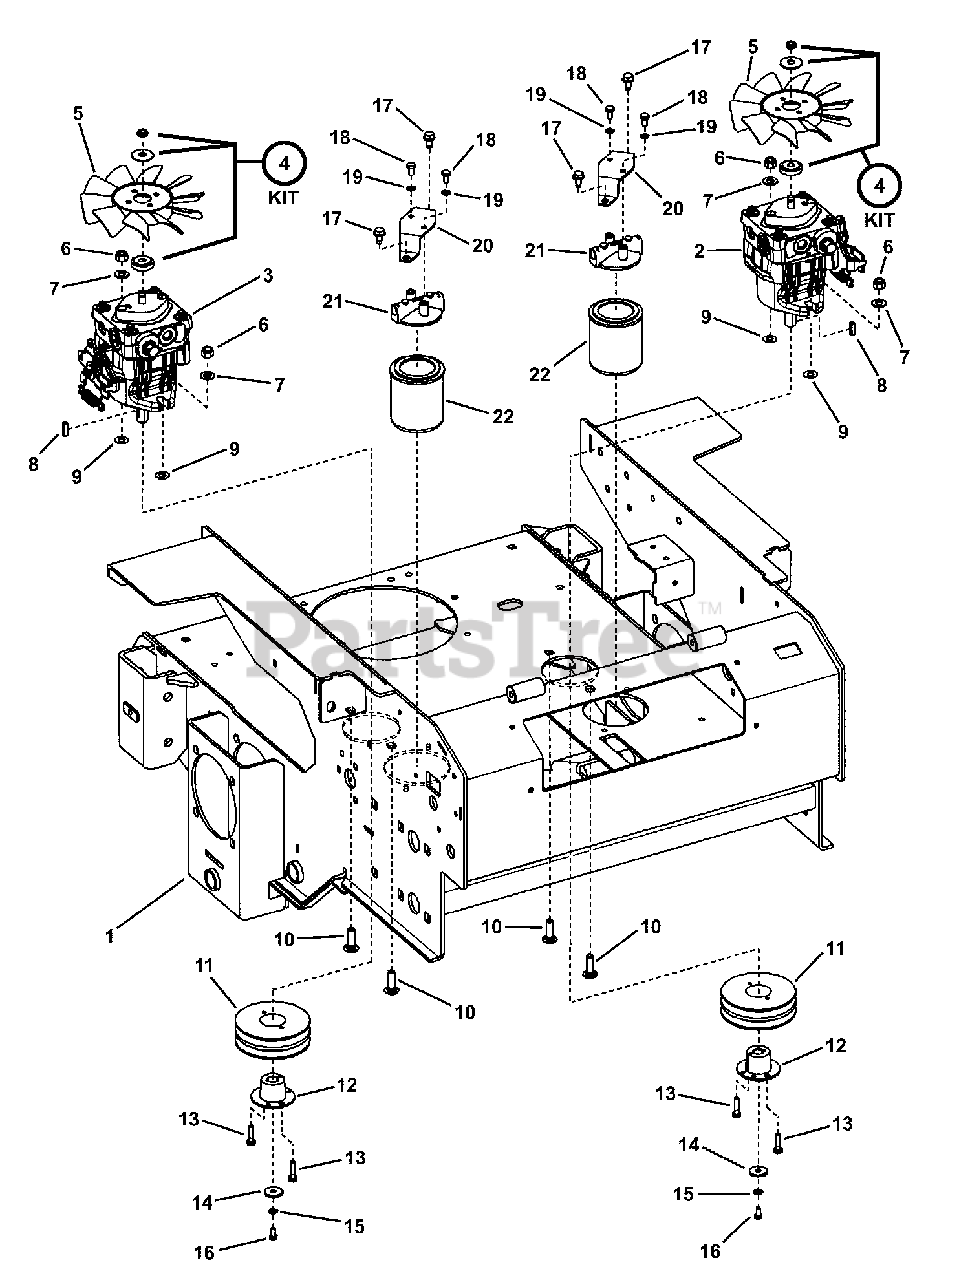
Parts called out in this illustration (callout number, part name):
1	WELDMENT, Rear Chassis
2	PUMP, Hydro-Gear BDP-12A W/ RTN
3	PUMP, Hydro-Gear BDP-12A W/ RTN
4	* KIT, Fan Hub
5	FAN, 7" Nylon, Counter-Clockwise
6	NUT, 3/8-16 HEX NYLON LOCK
7	WASHER, 3/8" Flat SAE
8	KEY, M5 x M20
9	BOLT RETAINER, 3/8"
10	BOLT, 3/8-16 x 1-1/4" Short Neck Carriage GR 5
11	PULLEY, 4.25 O.D. x 1.375 OA x "H" Tapered Bore
12	PULLEY, "D" Bushing x 15mm Bore
13	SCREW, 1/4-20 x 1" Hex Head Cap GR 5
14	WASHER, 1/4 x 1 x 1/8" Flat
15	WASHER, 1/4" Split Lock
16	SCREW, M6 1.0X12MM, Hex Head, CZ
17	SCREW, 5/16-18 x 5/8" Hex Washer Self-Tap
18	SCREW, 1/4-20 x 1/2" Hex Head Cap, GR 5
19	WASHER, 1/4" Split Lock
20	BRACKET, Filter
21	FILTER HEAD
22	FILTER, OIL
